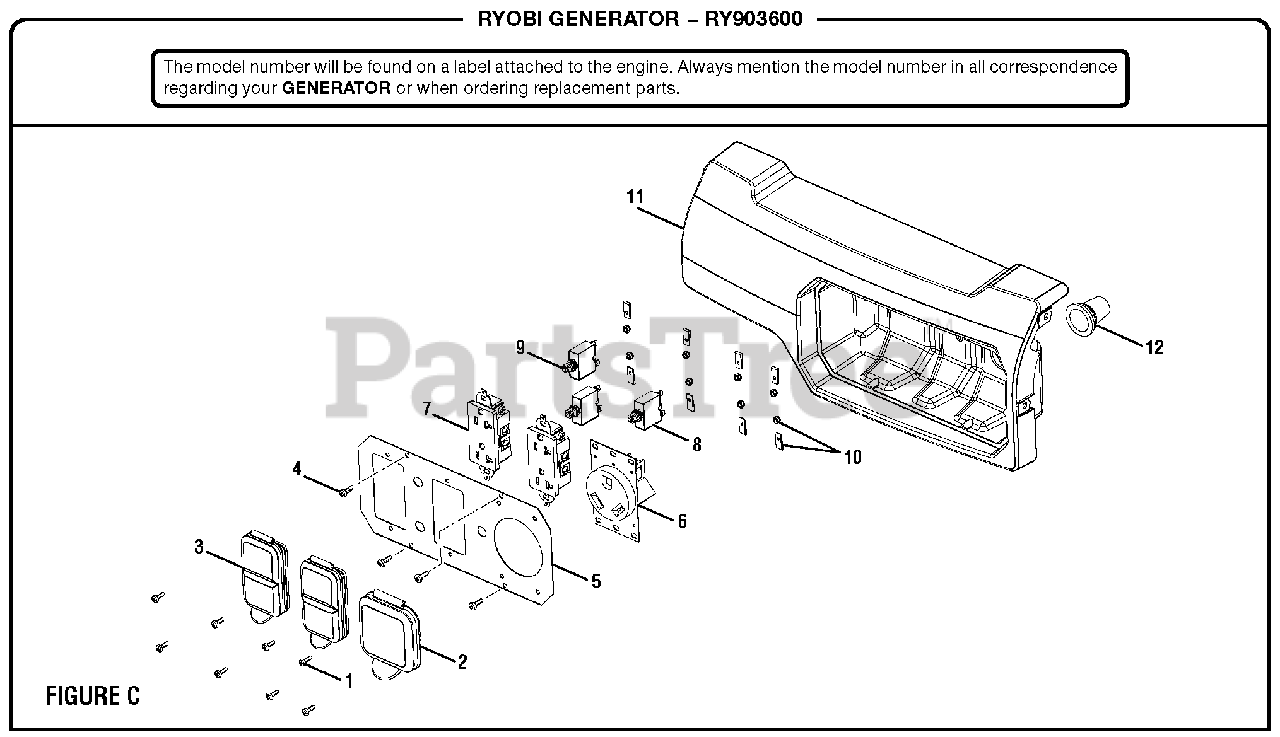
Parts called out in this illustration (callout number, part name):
1	Screw (#6-20 x 0.38 in., Type B)
2	Outlet Cover
3	Duplex Outlet Cover
4	Screw (M4.2 x 12 mm)
5	Front Panel
6	Recepticle (120V)
7	Duplex Receptacle (120V)
8	Circuit Breaker (30 Amp)
9	Circuit Breaker (20 Amp)
10	Lock Nut (#6-32)
11	Control Box (Back Panel)
12	Rubber Boot
